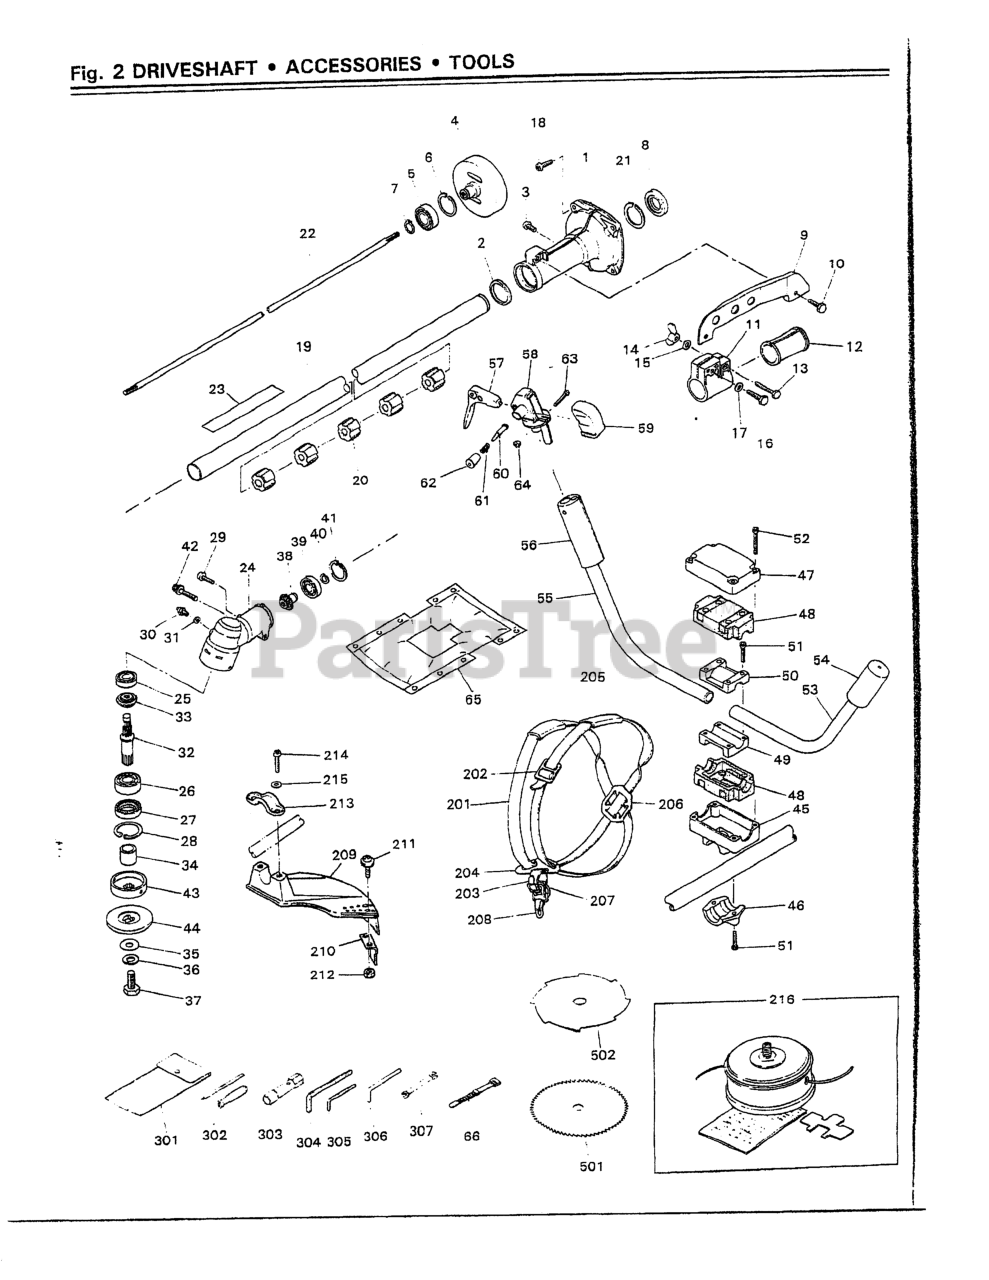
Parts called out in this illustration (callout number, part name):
3	SCREW, M6 X 10
4	DRUM, SPLINED
5	BEARING
6	RING, SNAP, M35 X 1.5
7	RING, SNAP, M15 X 1.0
9	HANGER (USE 3549- )
10	BOLT, M6 X 16
13	BOLT, M6 x 35
14	NUT (RPLS 01540-20632)
15	WASHER, M6 x .8
16	BOLT, M6 X 25
17	WASHER, M6 x .8
24	GEARCASE
25	BEARING (RPLS T3403-13510)
28	RING, SNAP, M35 X 1.5
29	BOLT, M5 X 10
30	FITTING, GREASE
31	WASHER, M6 X .8
35	WASHER, M10 x 3.2
36	WASHER
39	BEARING
41	RING, SNAP, M28 x 1.2
42	BOLT, M6 x 1.35
46	CAP, LOWER
47	CAP, UPPER
48	ABSORBER
49	CLAMP (A)
50	CLAMP (B)
51	BOLT, M5 X 25
52	BOLT, M5 X 30
53	HANDLE COMPL, LEFT
54	HANDLE COMPL, LEFT
55	HANDLE (R) CO
56	HANDLE (R) CO
60	STOPPER
62	KNOB
63	SCREW, M4 X 25
66	BAND
205	PROTECTOR
210	BLADE
211	SCREW, M5 x 12
212	NUT
214	BOLT, M6 x 1.30
215	WASHER, M6 X 15
216	NYLON CUTTER ASSY
302	SCREWDRIVER
304	WRENCH (TOOL)
305	WRENCH (TOOL)
306	BAR
307	SPANNER, 8 X 10 (RPLS 2540- )
501	BLADE, CIRCULAR SAW
502	BLADE, EDDY SAW
